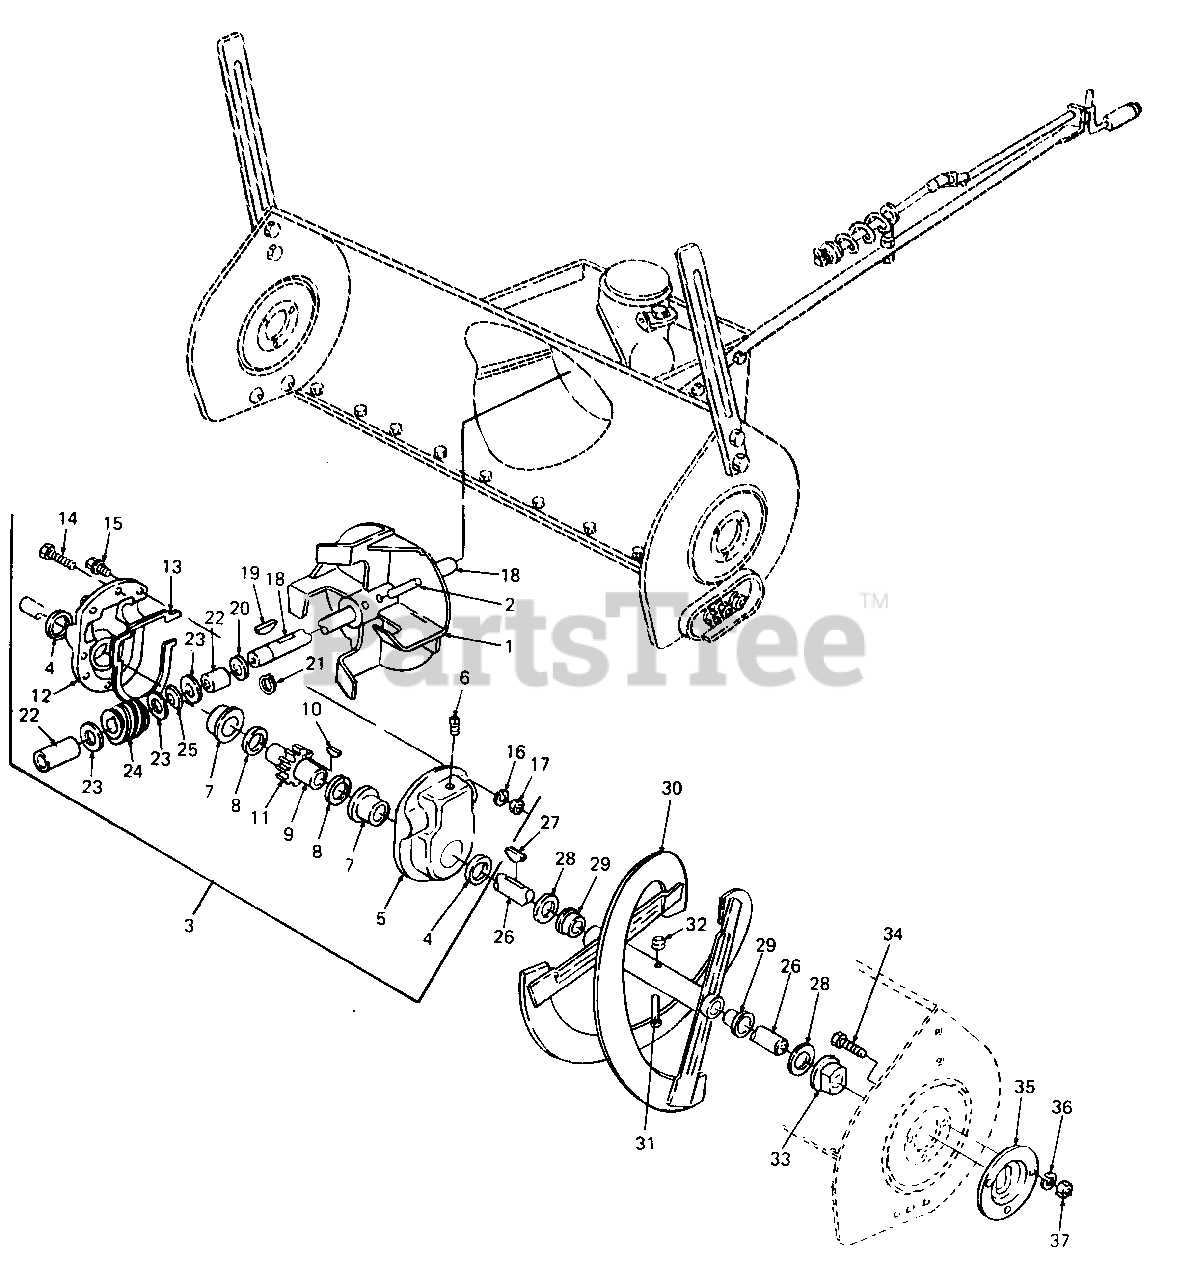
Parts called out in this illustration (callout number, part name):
3	Gear Box Assy
4	Seal, Oil
5	Housing, Gear - LH
6	Plug, Vented Plastic
7	Bearing, Flange
8	Washer, Flat, 1.50 X 2.25 X .030 Thk
9	Shaft, Worm Gear
10	Key, Woodruff, 1/4 X 3/4 HDN
11	Gear, Worm
12	Housing, Gear - RH
13	Gasket
14	Screw, Hex Cap, 5/16-18 X 1.25 Lg GR5
15	Screw, Hex Cap, 5/16-18 X 1.0 Lg GR5
16	Washer, Shake Proof, .32 X .62 X .020 Thk
17	Nut, Hex Insert Lock, 5/16-18
18	Shaft, Blower Axle
19	Key, Hi-Pro, 3/16 X 3/4 HDN
20	Seal, Oil
21	Ring, Snap
22	Sleeve
23	Washer, Flat, .88 X 1.4 X .155 Thk
24	Gear, Worm
25	Bearing, Thrust
26	Shaft, Spiral Axle
27	Key, Woodruff, 1/4 X 3/4 HDN
28	Washer, Flat, 1.0 X 1.75 X .100 Thk
29	Bushing, Plastic
31	Bolt, Shear, 5/16-18 X 1.75 Lg
32	Nut, Hex Insert Lock, 5/16-18
33	Bearing, Flange
34	Bolt, Hex Sems, 5/16-18 X .75 Lg
35	Housing, Bearing
36	Washer, Lock, 5/16
37	Nut, Hex, 5/16-18
